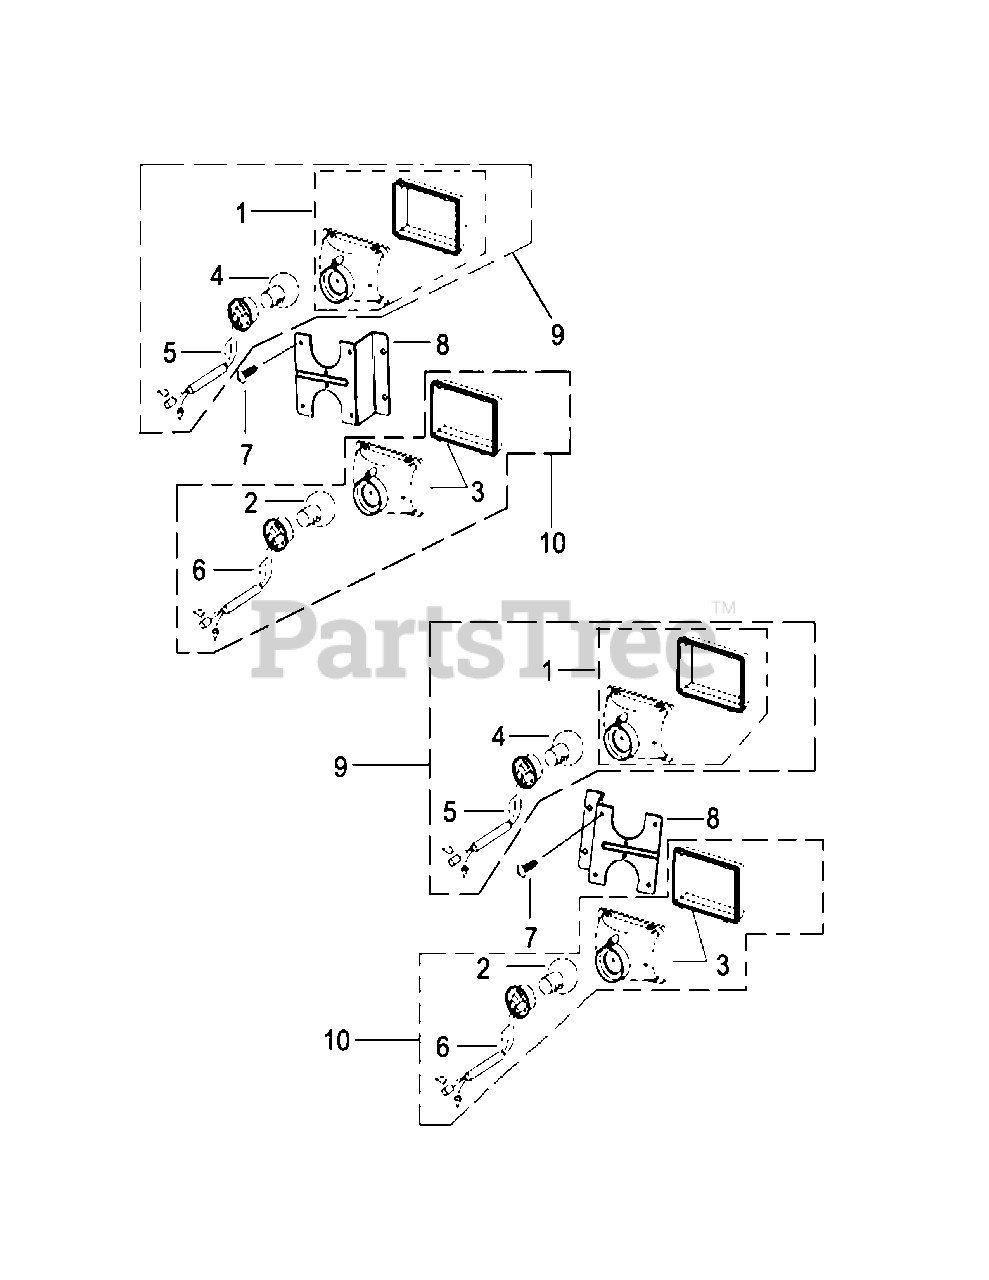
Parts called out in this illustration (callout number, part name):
1	Tail Light Comp.
2	Turning Signal Bulb (12V 10W)
3	Rear Turning Light Housing
4	Rear Brake Bulb (12V 21W)
5	Tail Light Cable
6	Rear Turning Light Cable
7	Cross Plate Head Tapping ScrewST3.9×13
8	Mounting Plate, Tail Light
9	Tail Light Comp.
10	Rear Turning Signal (L)
10	Rear Turning Signal (R)
